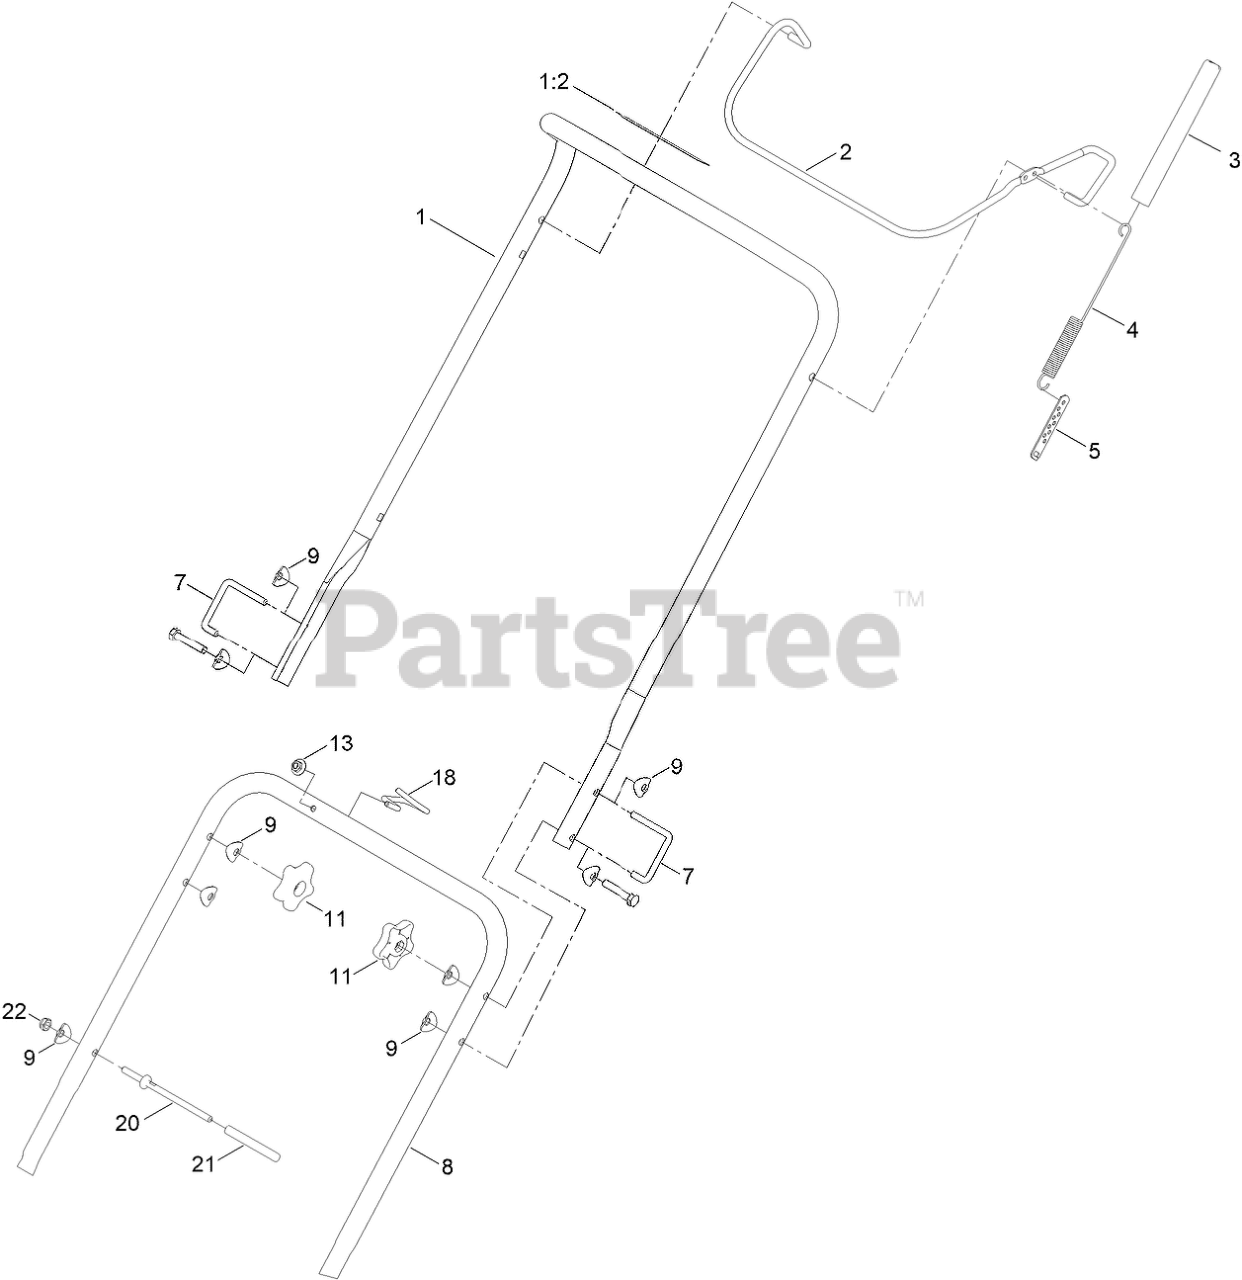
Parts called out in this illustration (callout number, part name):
1	UPPER HANDLE ASM (W/ DECAL)
1:2	DECAL-DRIVE, ROTOR
2	BAIL-CONTROL
3	COVER-SPRING
4	SPRING-EXTENSION, CLUTCH
5	ADJUSTER-CLUTCH CABLE
7	LOCK-HANDLE
8	HANDLE-LOWER
9	WASHER
11	KNOB-HANDLE
13	NUT-HF
18	GUIDE-ROPE
20	SUPPORT-SWITCH BOX
21	CAP-SUPPORT
22	NUT-LOCK, NI
